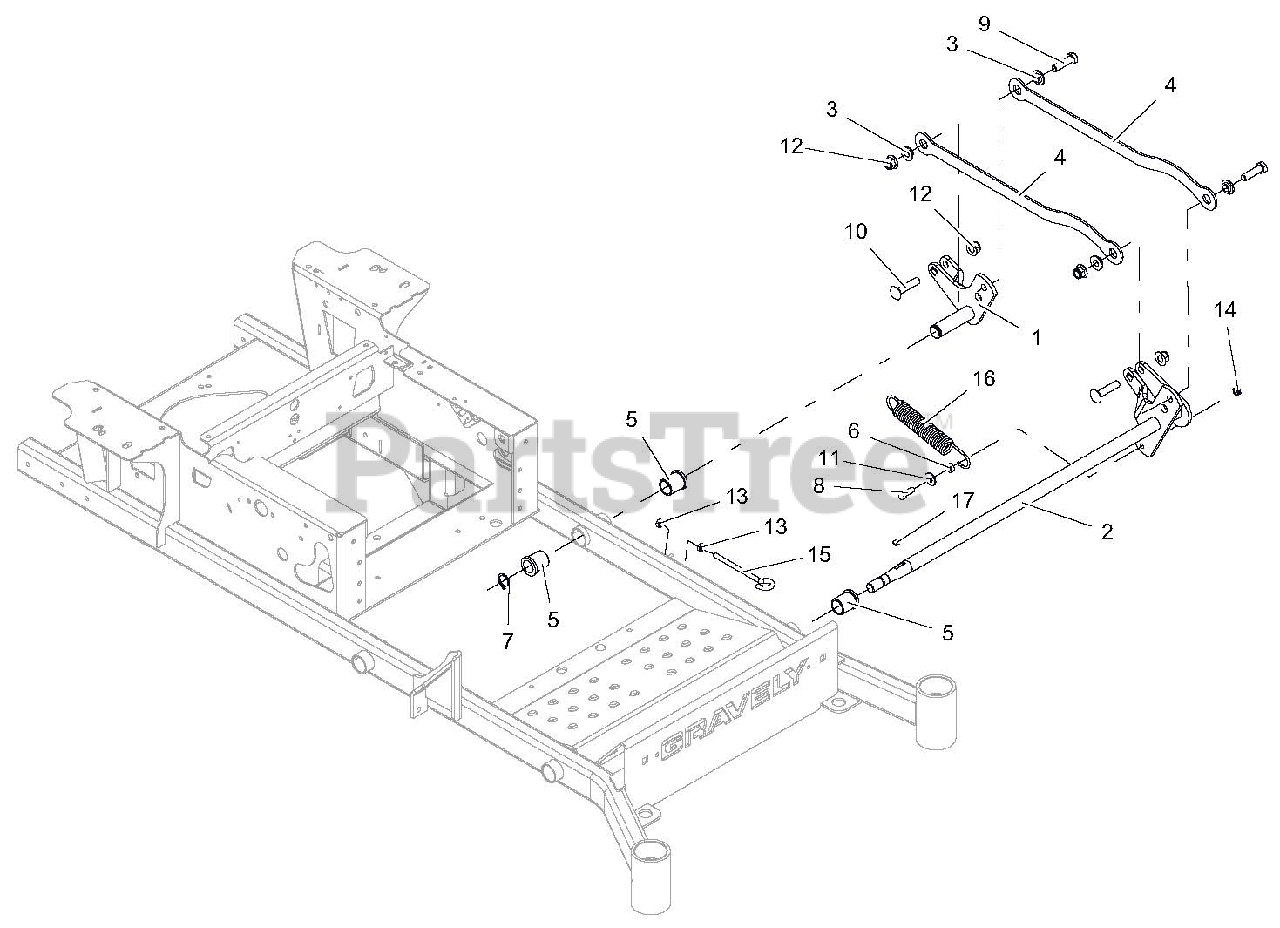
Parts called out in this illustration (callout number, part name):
1	WLDMT, LH REAR DECK LIFT
2	WLDMT, PT100 FRONT LH DECK LIFT-BLACK
3	BSHG, FLANGE .515X.750X.31X1.12
4	LINK, LIFT - BLK
5	BSHG-FLG 1.00X1.25X1.5X1.5
6	BSHG, SLV .377X.624X.235
7	RG-RTNG-EXT 1.00X.078
8	BLT-HEX .38-16X1.00 GR5 YWZC
9	BLT-HEX .50-13X1.75 GR5 YWZC
10	BLT-RDHDSQNK .50-13X2.25 G5 Y
11	WSHR-FL-STL.438X1.00X.083 YWZC
12	NUT-LK-NYL-FLG .50-13 YWZC
13	NUT, JAM .375-16 YWZC
14	@NUT-LK-CTR-JAM .375-16 YWZC
15	BOLT, EYE .38-16X6.00 .62 DIA
16	SPRG, TENSION .162 X 1.250 X 8.250
17	KEY, WDRF .25 X 1.00 HRD #15
